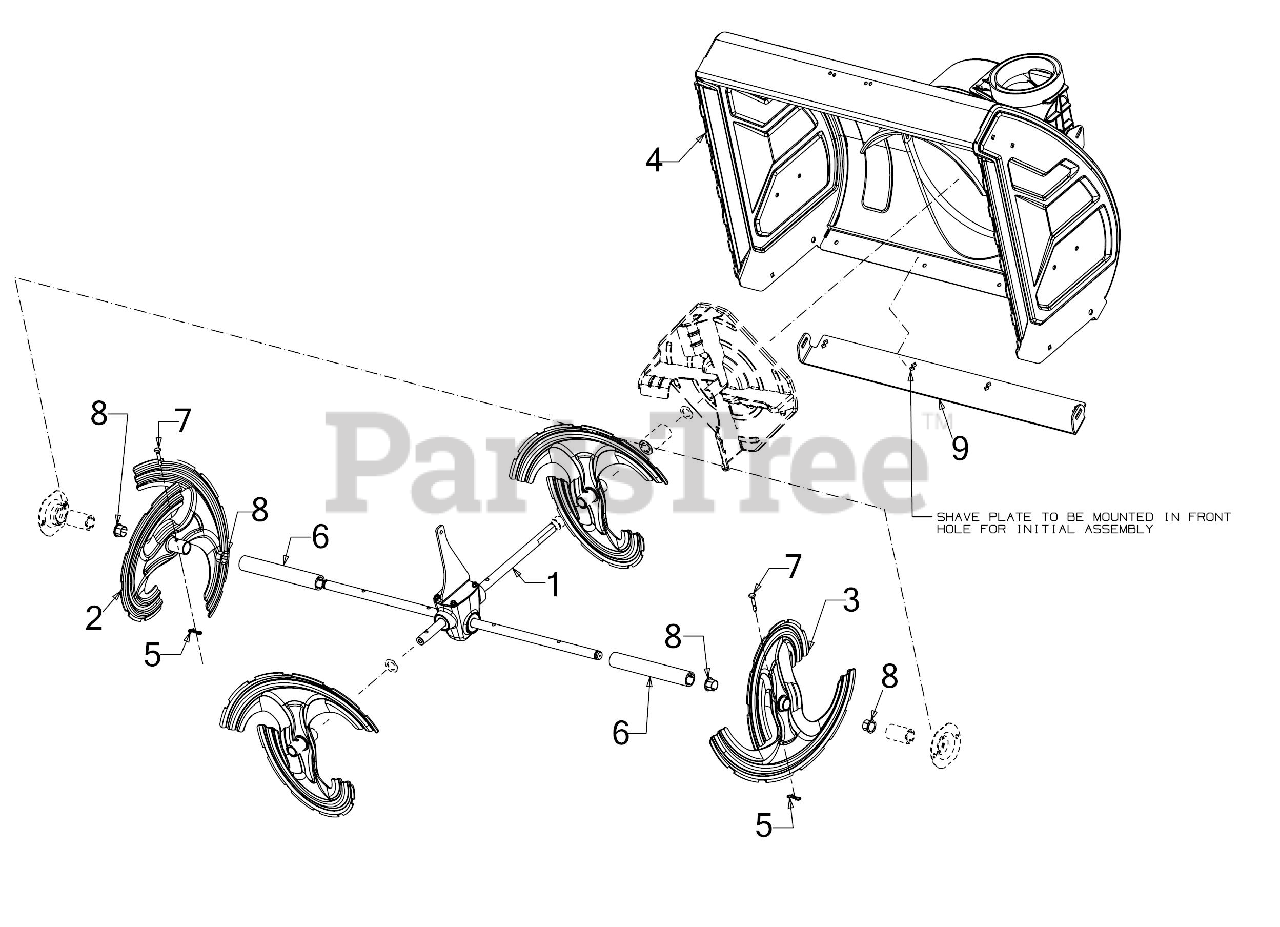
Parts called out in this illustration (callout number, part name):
1	30" AUGER GEARBOX ASSEMBLY
2	14" AUGER SPIRAL ASSEMBLY (RH)
3	14" AUGER SPIRAL ASSEMBLY (LH)
4	30" AUGER HOUSING ASSEMBLY
5	BOW TIE COTTER PIN 1/4-5/16
6	SPACER 1.25OD X .75ID X 8.15LG
7	SHEAR PIN .25 x 1.50 GR2
8	FLANGE BUSHING
9	29.50" SHAVE PLATE
